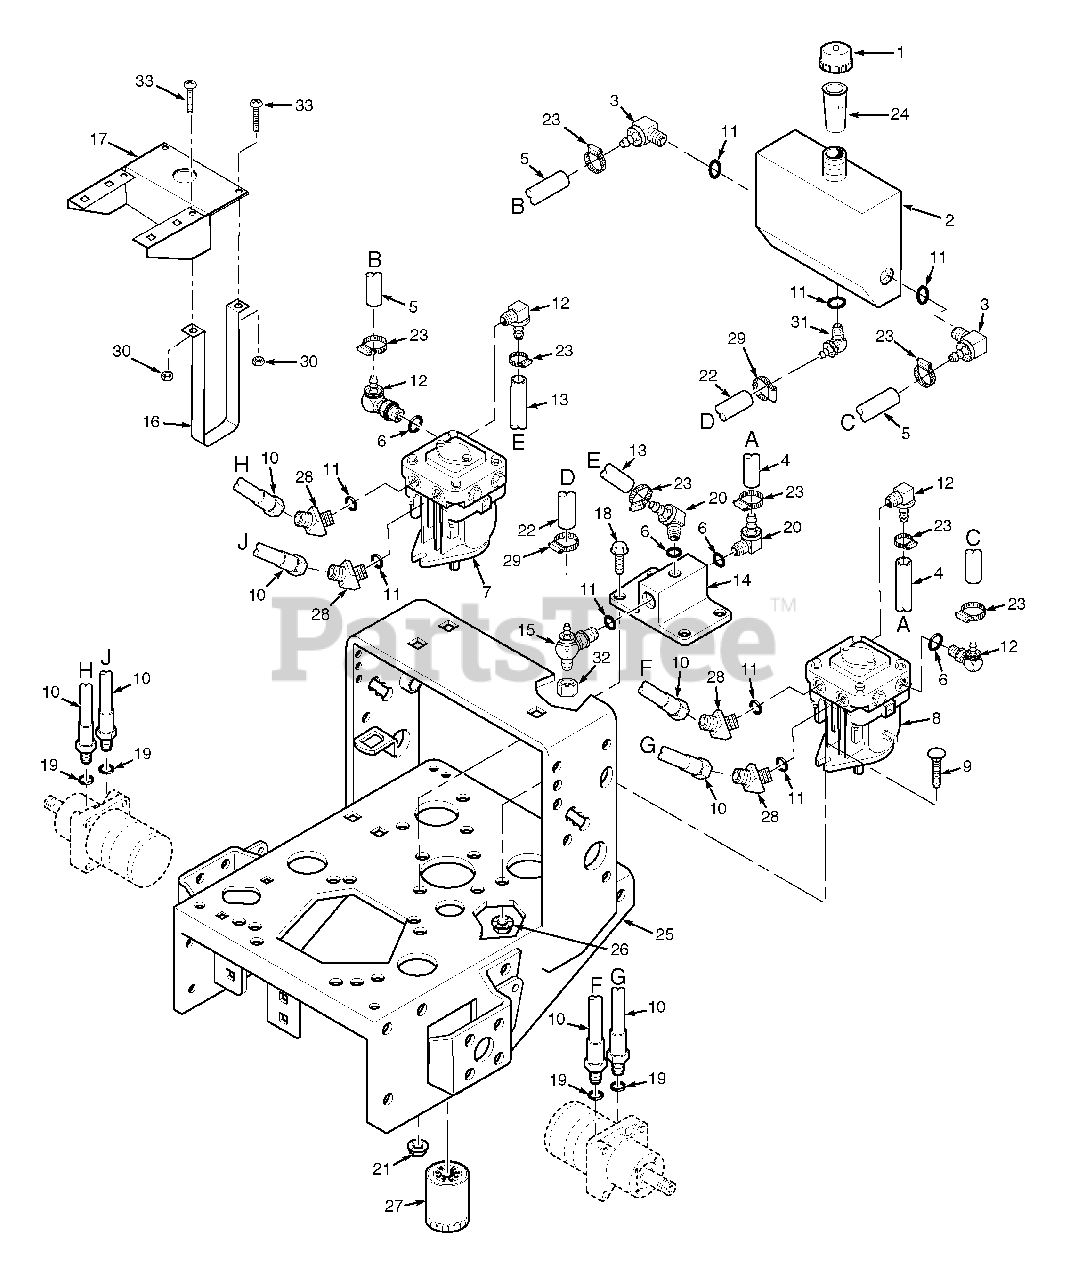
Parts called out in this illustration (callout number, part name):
1	Cap, Oil Reservoir
2	Oil Reservoir (With Fittings)
3	Elbow, 9/16 O-Ring x 3/8 Hose
4	Hose, 3/8" ID - 10-1/4" Long
5	Hose, 3/8" ID - 7" Long
6	O-Ring
7	Pump, PG-1JQQ-DY1X-XXXX (R.H.)
8	Pump, PG-1GQQ-DY1X-XXXX (L.H.)
9	Bolt, Carriage, 3/8-16 x 1.25"
10	Hose, Pump to Wheel Motor
11	O-Ring
12	Elbow, 7/16-20 O-Ring x 3/8 Hose
13	Hose, 3/8" ID - 11" Long
14	Oil Filter Base
15	Tee, 3/8 O-Ring x JIC x 1/2 Hose
16	Strap, Hydraulic Tank
17	Bracket, Hydraulic Tank
18	Capscrew, 5/16-18 x .75" Serr. Flange
19	O-Ring
20	Elbow, 9/16 O-Ring x 3/8 Hose
21	Nut, 5/16-18 Serr. Flange
22	Hose, Formed 1/2" ID
23	Clamp, .69 max dia.
24	Tube, Filler Neck
25	Engine Deck (16" Wide) W/Decals
26	Nut, 3/8-16 Serr. Flange
27	Oil Filter
28	Elbow, 45 Deg.-3/4-16 JIC Male x Male 3/4-16 O-Ring
29	Clamp, .87 max di.
30	Nut, 1/4-20
31	Elbow, 3/4-16 O-Ring x 1/2 Hose
32	Cap, 3/4-16
33	Screw, 1/4-20 x 2.0" Round Head Phillips
